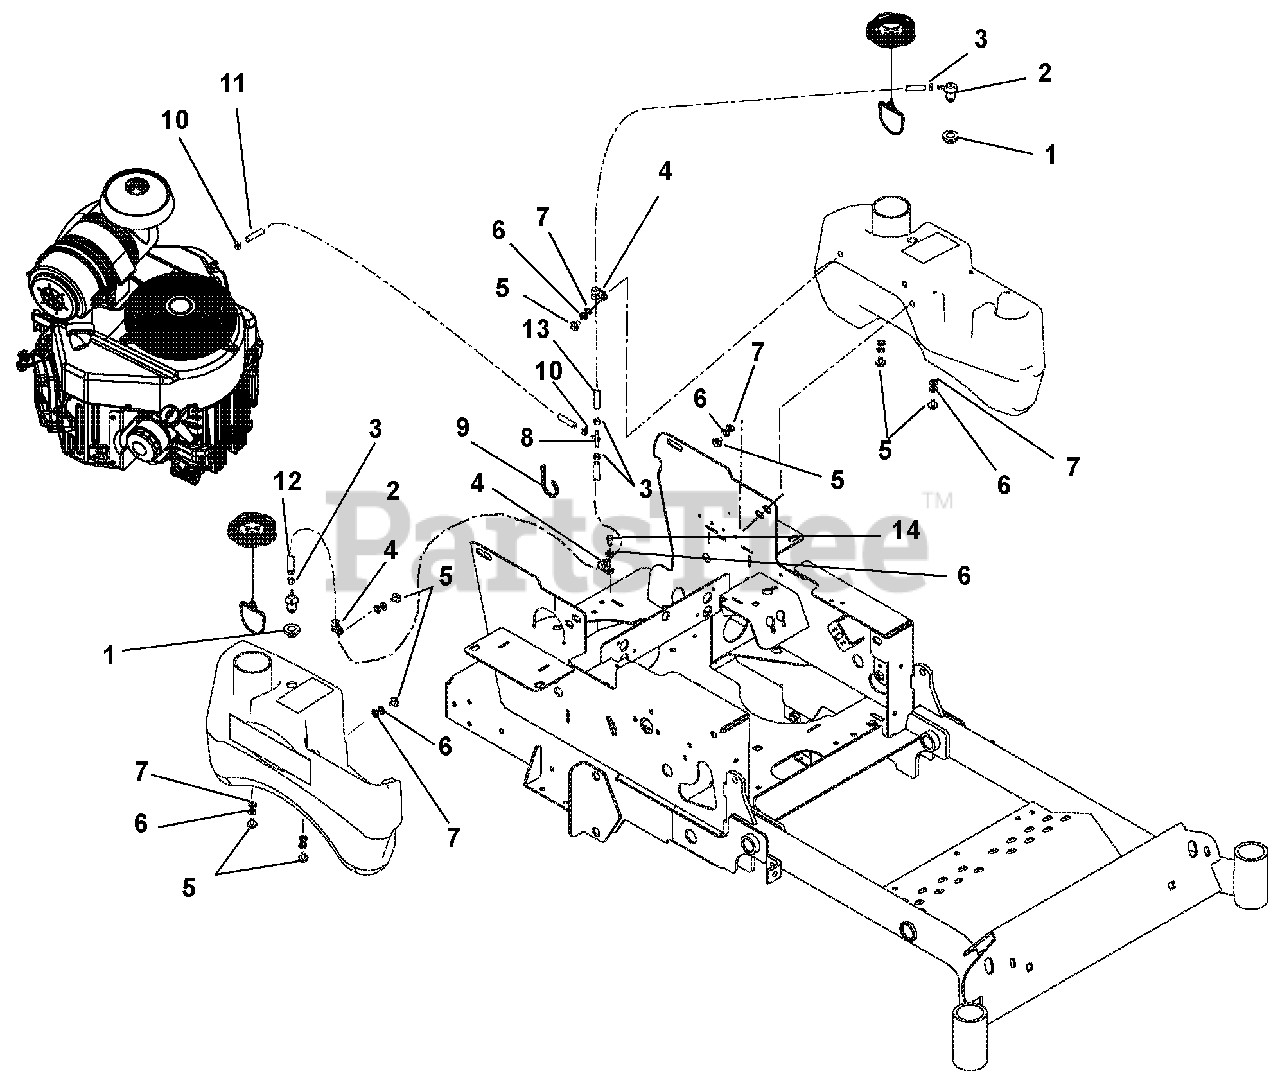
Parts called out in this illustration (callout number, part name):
2	Valve
3	Hose, Clamp
5	Bolt, .31-18 x .62
6	Washer, Locking .31 x .078 Regular
7	Washer, Flat Steel .38 x .875 x .083
8	Fitting, Tee 1/4 x 3/8
9	Tie, Cable LG 5.50
10	Clamp, Spring .188
11	Hose, Fuel
12	Hose, Fuel
13	Hose, Fuel
14	Bolt, Hex M8-1.25 x 2.0
